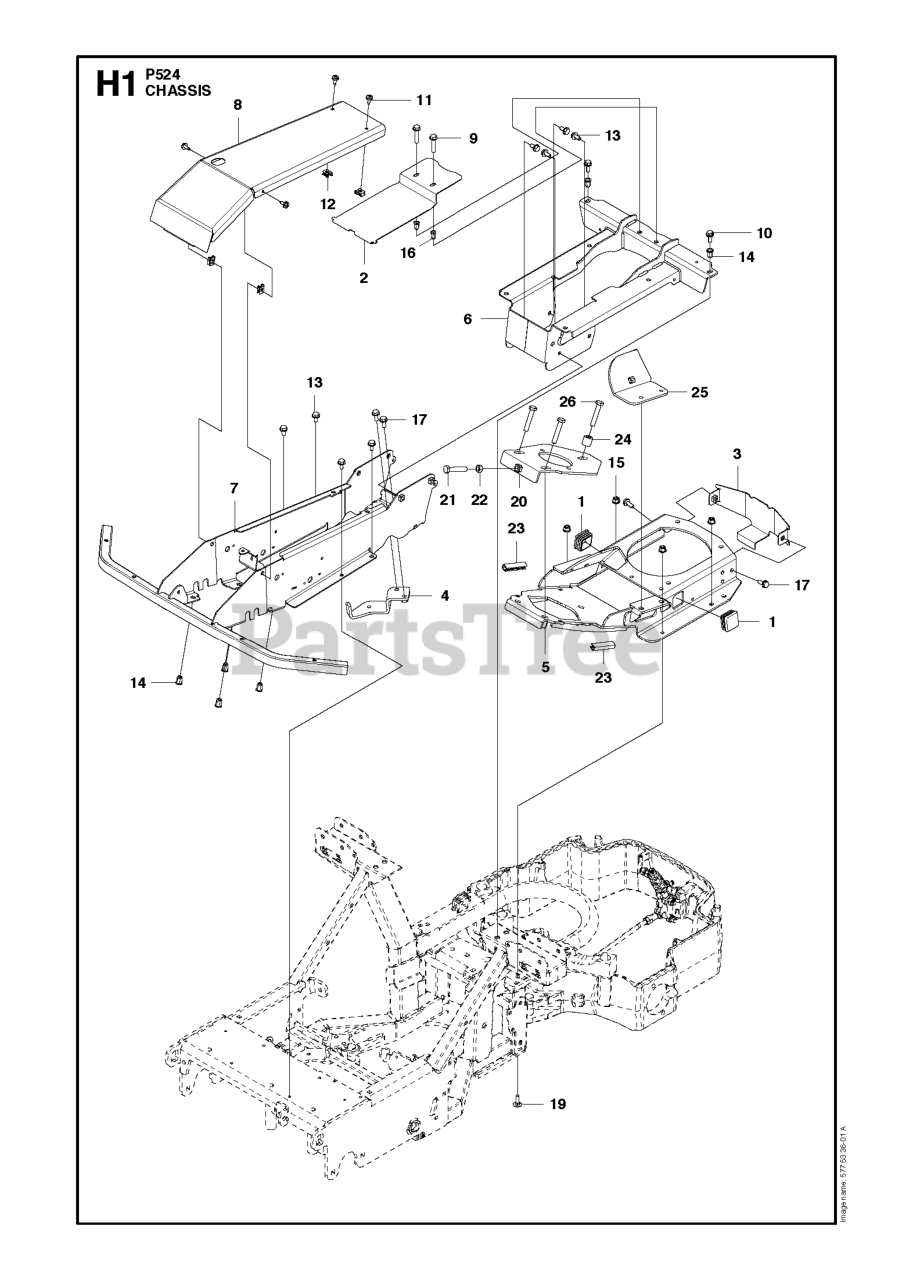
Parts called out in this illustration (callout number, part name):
10	BOLT
15	NUT FLANGE
22	NUT
